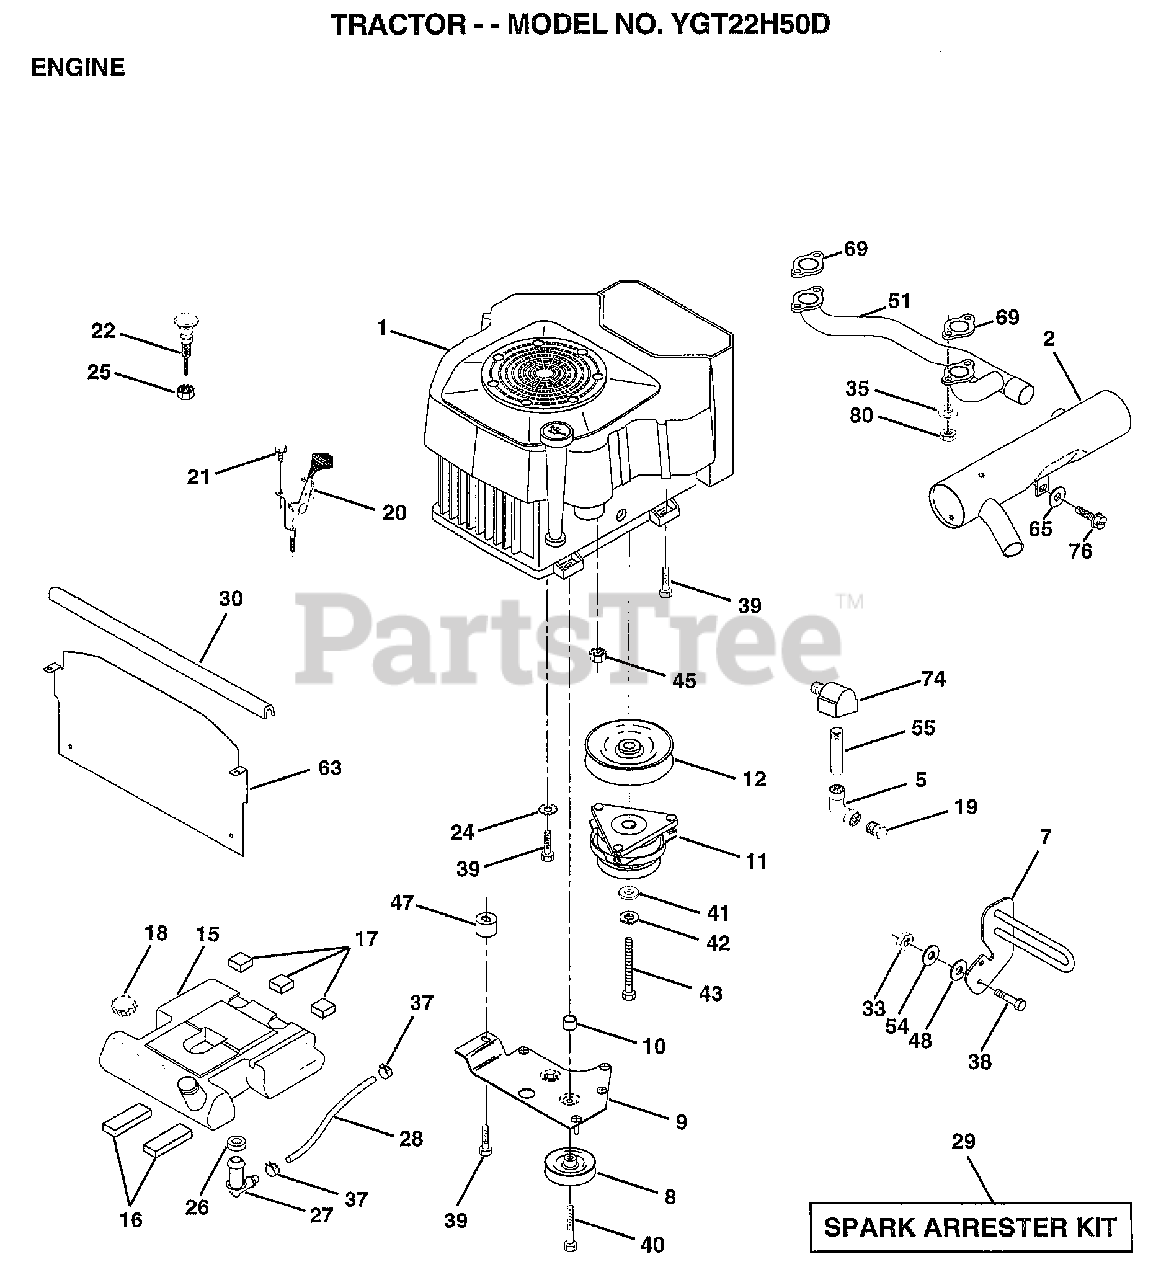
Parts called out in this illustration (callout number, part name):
2	MUFFLER.SIDE.VGT
5	ELBOW
7	GUARD.MUFFLER.ASM
9	KEEPER ASM BELT
10	BUSHING.
12	PULLEY.ENG.CLUTCH
15	TANK FUEL REAR
16	PAD IDLER TI
17	PAD-SPACER LT
18	CAP ASM FUEL
19	PLUG T
21	SCREW LT
22	CHOKE CONTROL
23	WASHER
24	LOCKWASHER
25	"NUT,KEPS 3/8-24IM"
26	BUSHING OUTLET T
27	STEM.TANK.FUEL
29	SPARK ARREST KIT
30	FOAM-STRIP LT
33	NUT
35	LOCKWASHER
37	HOSE CLAMP
38	"BOLT,HEX"
39	SCREW.3/8-16X2.25
40	SCREW.TT.3/8-16X4
41	WASHER
42	LOCKWASHER
43	BOLT.7/16-20X4.25
45	NUT
47	SPACER.ENGINE
48	WASHER T
51	MANIFOLD.PIPE.VGT
54	WASHER
55	PIPE NIPPLE LT
63	HEAT.SHIELD.VGT.
65	WASHER
69	GASKET MUFFLER
74	ELBOW STREET BASS
76	SCREW
80	NUT
